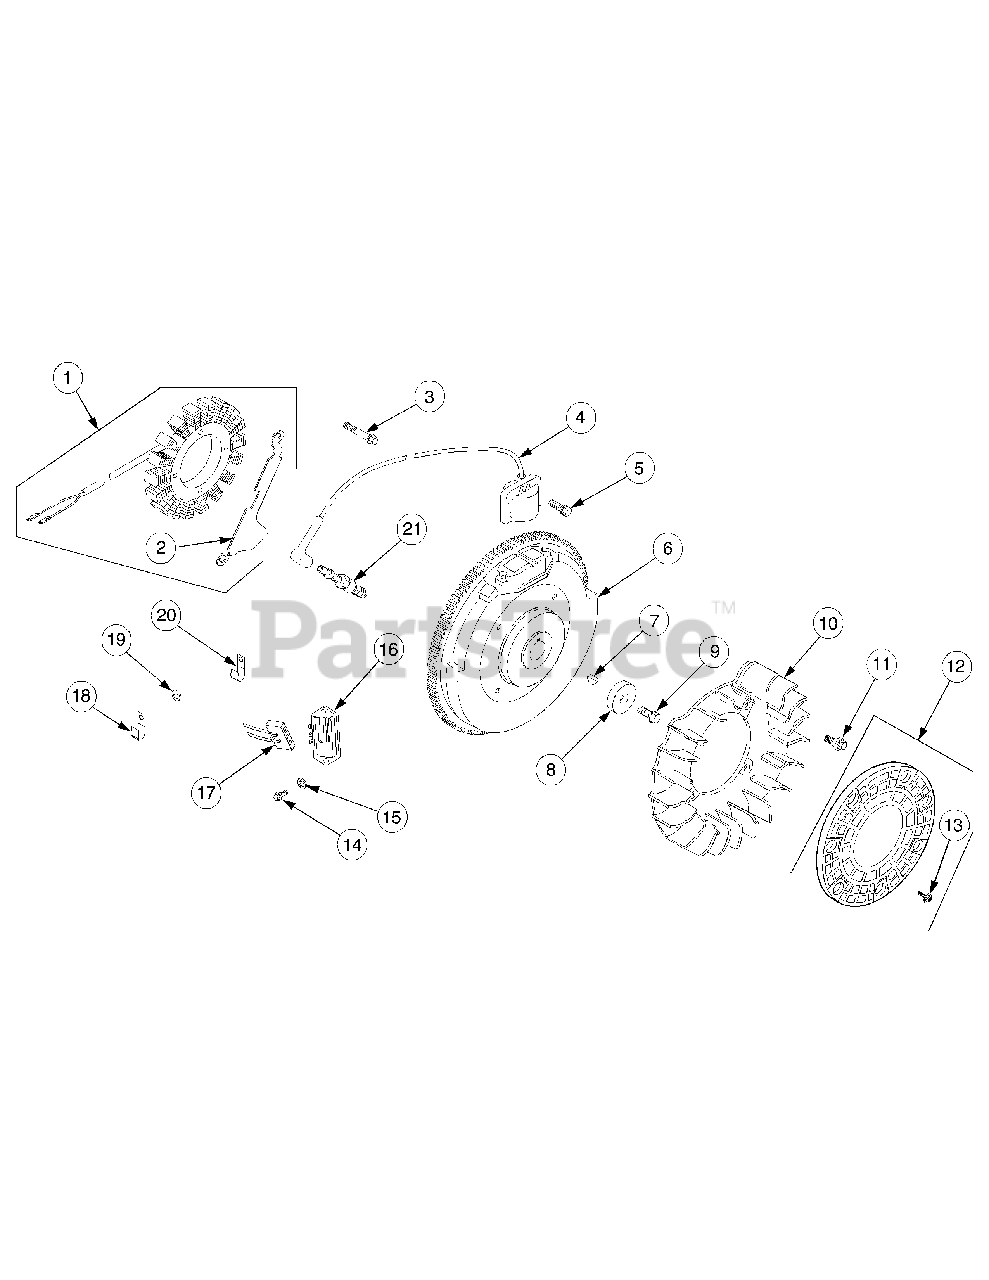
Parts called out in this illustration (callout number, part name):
1	Stator Kit, 15 Amp (Incl. Ref #2)
2	Bracket, Stator Wire
3	Screw, Stator Mtg. M5 x .8 x 25
4	Module, Ignition
5	Screw, Module M5 x .8 x 20
6	Flywheel Assembly
8	Washer, Flywheel Mtg. Screw
9	Screw, Flywheel Mtg, M10x1.5 x 46
11	Bolt, Shoulder
12	Kit, Grass Screen
13	Screw, Sems Hx Hd
14	Screw Phillips Hd., #11-16 x .875
15	Washer, Plain
16	Regulator - Rectifier
17	Connector, Regulator-Rectifier
18	Clip, Cable
19	Washer, Plain 1/4"
21	Spark Plug
